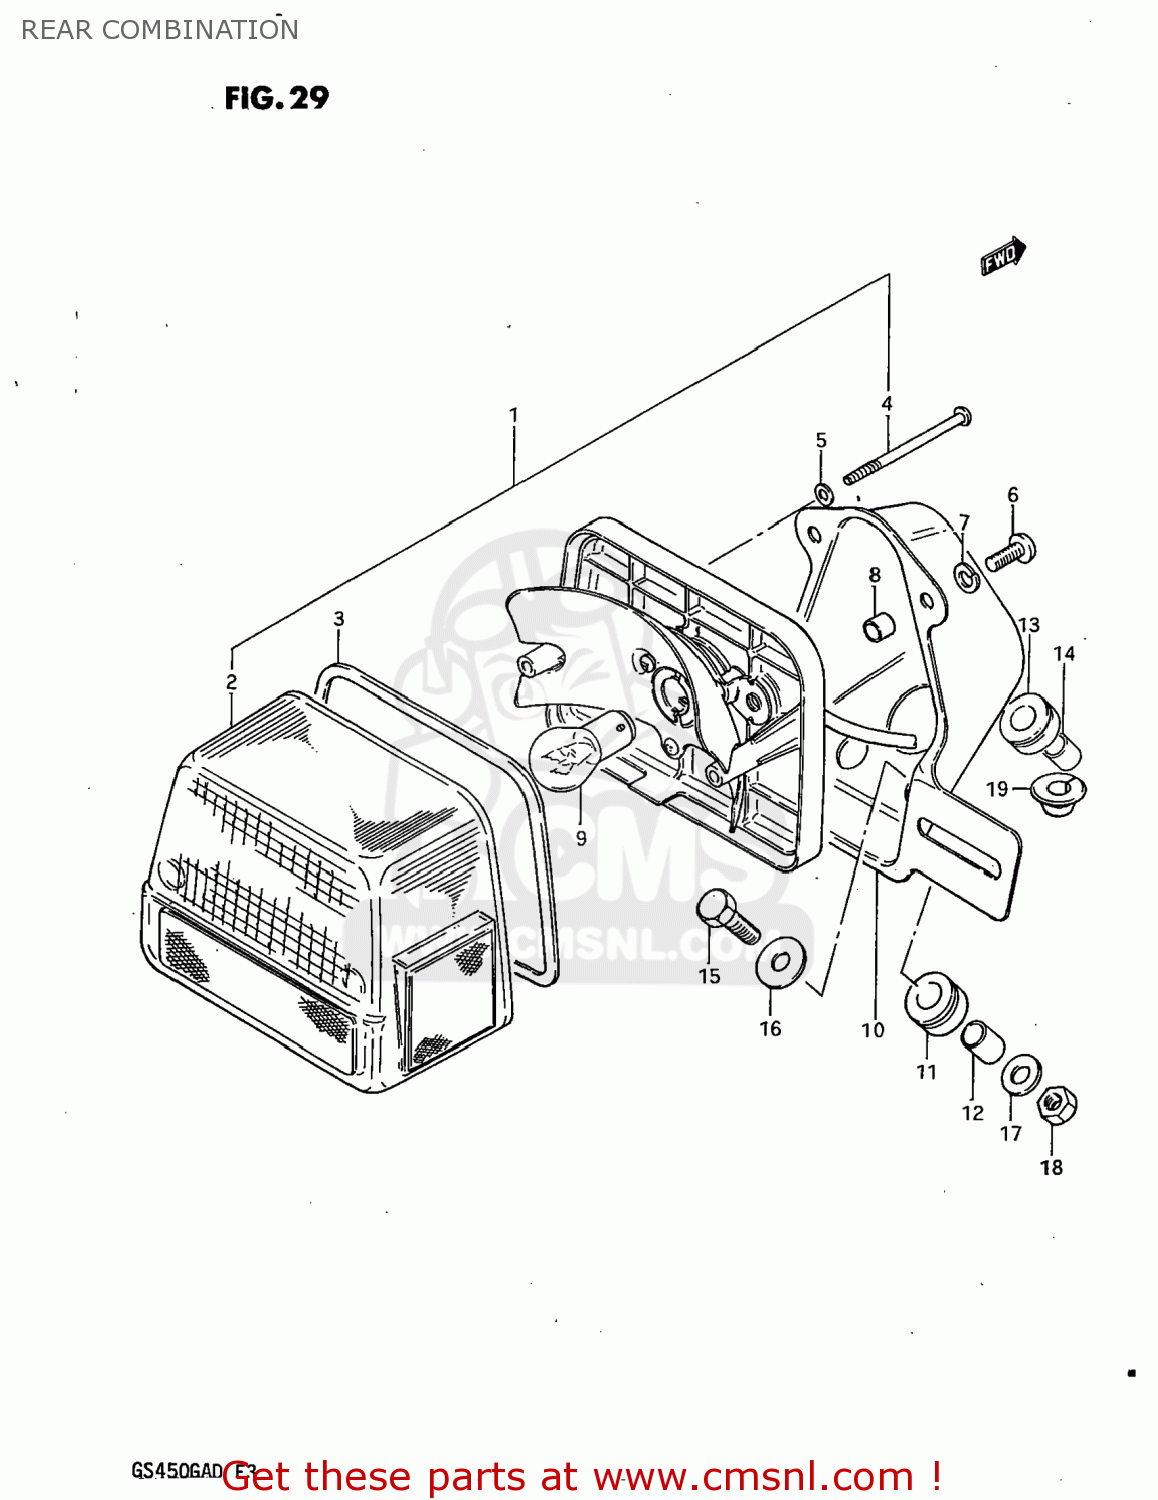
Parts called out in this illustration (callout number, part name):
1	LAMP UNIT,RR COMBNATION
2	LENS
3	GASKET (NAS)
4	SCREW
5	GASKET (NAS)
6	SCREW
7	LOCK WASHER
8	SPACER
9	BULB(12V23W)
10	BRACKET,REAR COMBINATION LAMP
11	CUSHION,REAR COMBINATION LAMP
12	SPACER,REAR COMBINATION LAMP
13	CUSHION
14	SPACER
15	BOLT
16	WASHER (6.5X20X1.2)
17	WASHER
18	NUT
19	GROMMET
